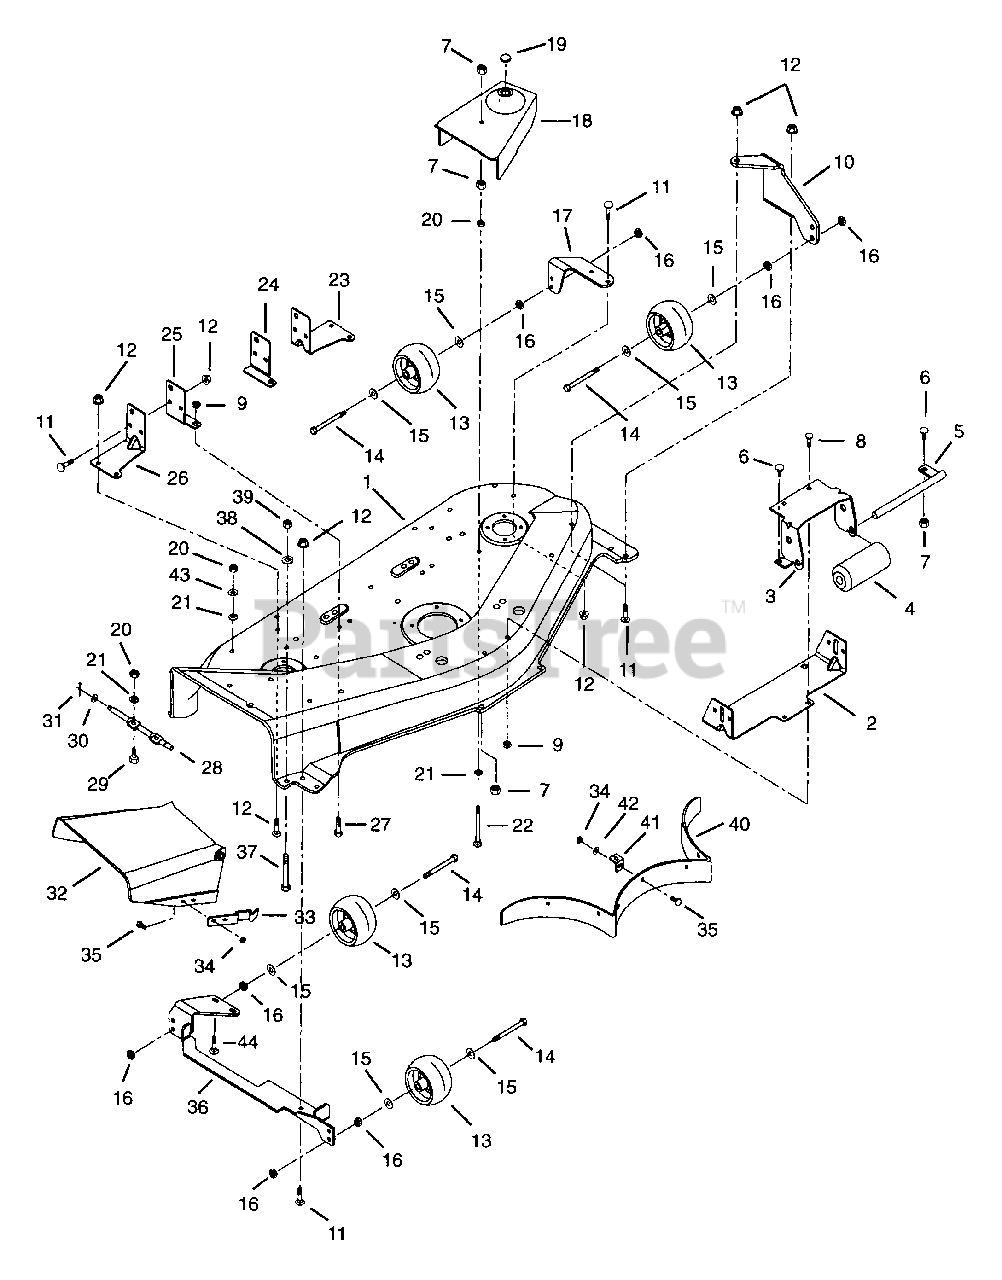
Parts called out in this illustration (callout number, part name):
1	MOWER PAN W/DECALS 48"- ORANGE
2	FRONT HANGER
3	BRACKET, ROLLER
5	ROLLER SHAFT
6	BLT-RDHDSQNK .31-18X.75 GR5 PL
7	NUT-LK .312-18 GR A PL
8	BLT-RDHDSQNK .50-13X.75 SHT PL
9	NUT-LK-NYL .50-13 GR 5 PL
10	LH FRONT BRACKET
11	BLT-RDHDSQNK.31-18X.75GR5SHTPL
12	NUT-FLG. .312-18 PL
14	BLT-HEX .38-16X3.50 PL GR5
15	WSHR-FL-STL .38X.875X.083 PL
16	NUT-LK-CTR .375-16 GR A PL
17	LH REAR BRACKET
18	BELT COVER R H 48"
18	BELT COVER L H 48"
19	BUTTON PLUG 1.0
20	NUT-HEX .312-18
21	WSHR-LK .312X.097 PL HVY
22	BLT-RDHDSQNK .31-18X3.25 SHTPL
23	LH REAR HANGER
24	LH REAR HANGER SUPPORT
25	RH REAR HANGER SUPPORT
26	RH REAR HANGER
27	BLT-HEX .50-13X1 PL GR5
28	HINGE PIN
29	BLT-HEX .31-18X.75 PL GR5
30	WSHR-FL-STL.406X.812X.065PL
31	PIN-COTR .09X.75 PL
32	CHUTE EXTENSION
33	SPRING, FLAT
34	NUT-LK-CTR .250-20 PL
35	BLT-RDHDSQNK .25-20X.50 SHT PL
36	ROLLER MOUNT WELDMENT
37	BLT-HEX.38-16X2.5FTHD GR2 YWZC
38	WSHR-LK .375X.115 HVY PL
39	NUT-HEX .375-16
40	BAFFLE
41	BAFFLE TAB
42	WSHR-FL-STL.281X.62X.065 PL
43	WSHR-FL-STL.312X.734X.065PL
44	BLT-RDHDSQNK .31-18X1.00 PL
